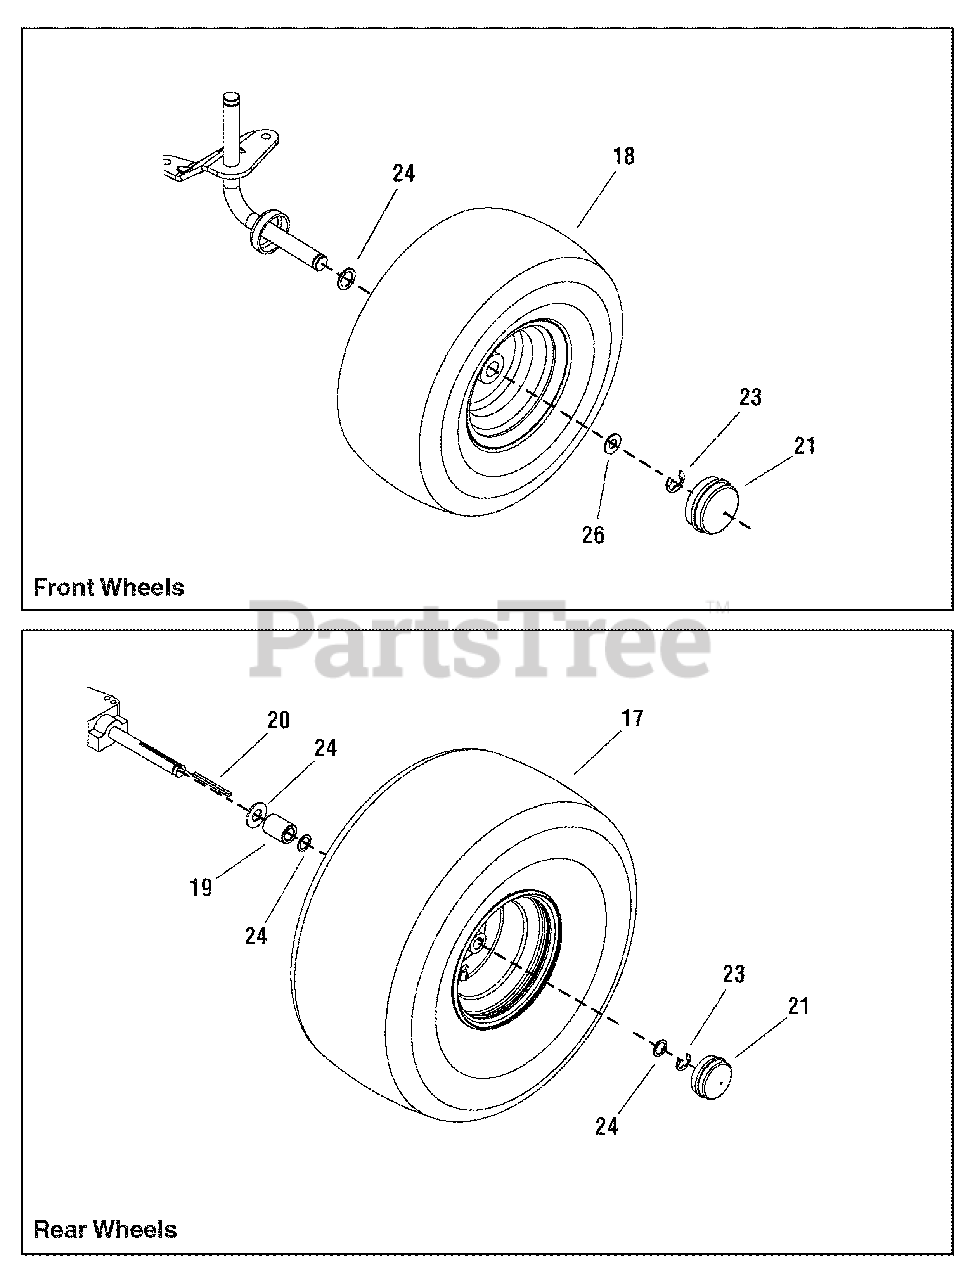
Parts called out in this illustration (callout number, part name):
17	Wheel & Tire, 22 x 10 - 8
18	WHEEL & TIRE ASSEMBLY, 14.4 X 6
19	SPACER, 0.77 ID x 1-1/4 OD x 1.65 LG Powdered Metal Black
20	KEY, 3/16
21	HUB CAP
23	RING, "E", .750 D - .050 T
24	WASHER, Flat, 3/4 x 1-1/4 x 16GA
26	WASHER, FLAT
